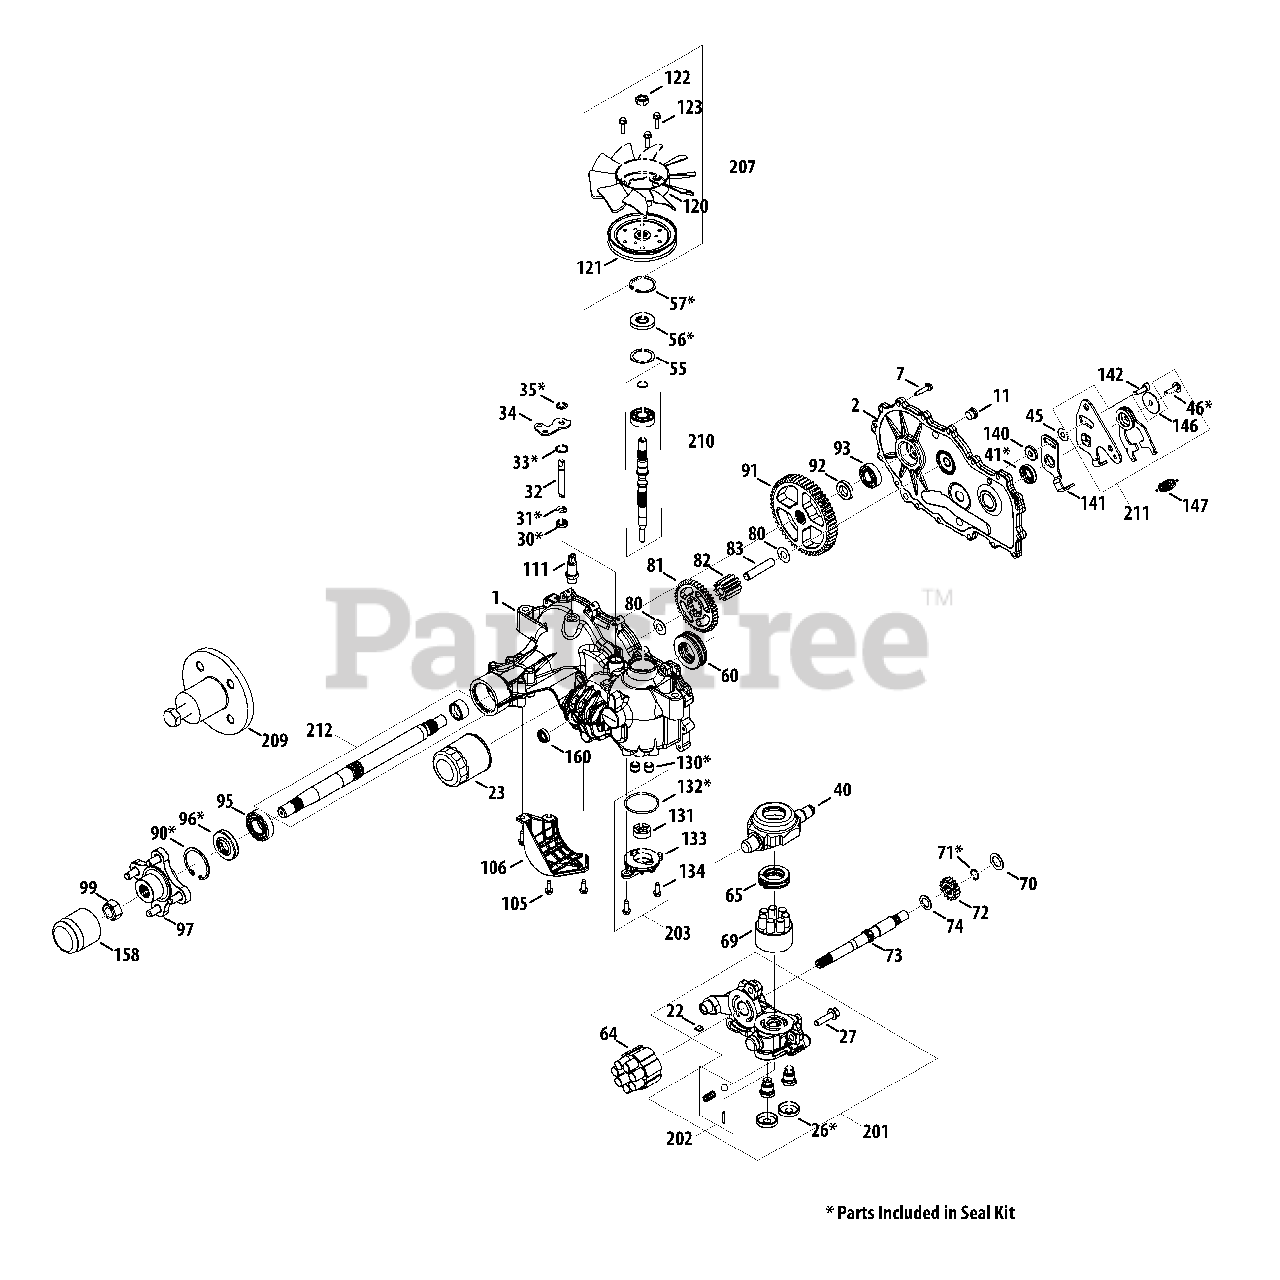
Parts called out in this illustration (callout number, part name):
1	Kit, Housing, Main, RH
2	Kit, Cover, Side, RH
7	Hex Cap Screw, 1/4-20 x 1.125
22	Plate, Bypass
23	Oil Filter
26	Seal, Plug, 1.25 x .25
27	Hex Cap Screw, 3/8-16 x 1.5
30	Seal, Lip .375 x .75 x .25
31	Ring, Ret .375 External
32	Rod, Bypass
33	Ring, Ret .75 Internal
34	Arm, Bypass
35	Ring, Retaining .375 External
40	Trunnion, Swashplate
41	Seal, Lip 12 x 32 x 7
45	Washer, .34 x .88 x .06
46	Hex Cap Screw, 5/16-24 x 1.00
55	Washer, 1.23 x 1.56 x .04
56	Seal, Lip 17 x 40 x 7
57	Ring, Retaining
60	Bearing, Thrust
64	Cylinder Block Assembly
65	Thrust Ball Bearing, 30 x 52 x 13
69	Block 7 Piston Assembly
70	Washer, .63 x 1.0 x .05
71	Retaining Ring, .625
72	Gear, 14t
73	Motor Shaft
74	Washer, .72 x 1.16 x .04
80	Washer, .5 x 1.0 x .03
81	Gear, 45t
82	Gear, 11t
83	Jack Shaft
90	Retaining Ring, 2.06 Internal
91	Gear, 54t
92	Spacer, .75 x 1.32 x .257
93	Ball Bearing, .75 x 40 x 12
95	Ball Bearing, 1.0 x 52 x 15
96	Seal, Lip 25 x 52 x 10
97	Kit, Hub, 4 Bolt
99	Nut, 3/4-16, Hex Lock
105	Hex Cap Screw, 1/4-20 x .75
106	Guard, Filter, RH
111	Fitting, 9/16-18 SAE .5 Barb
120	Fan 7", 10 Blade
121	Disc, Pulley
122	Nut, 1/2-20, Hex Jam
123	Hex Cap Screw, 1/4-20 x .875
130	Connecting Tube
131	Gerotor Assembly
132	O-Ring, -137, .103 x 2.050
133	Charge Pump Cover
134	Hex Cap Screw, 1/4-20 x .75
140	Spacer, .320 x 1.005 x .179
141	Neutral Left Arm
142	Hex Cap Screw, 5/16-24
146	Washer, .343 x 1.5 x .062
147	Extension Spring, .57 x 2"
160	Seal, Lip, .625 x .875 x .25
201	Kit, Center Section, RH
202	Kit, Charge Relief
203	Kit, Charge Pump
207	Kit, Fan & Pulley
209	Hub Puller, 4 Bolt
210	Kit, Input Shaft
211	Kit, RTN, Bidirectional
212	Kit, Shaft, Axle
